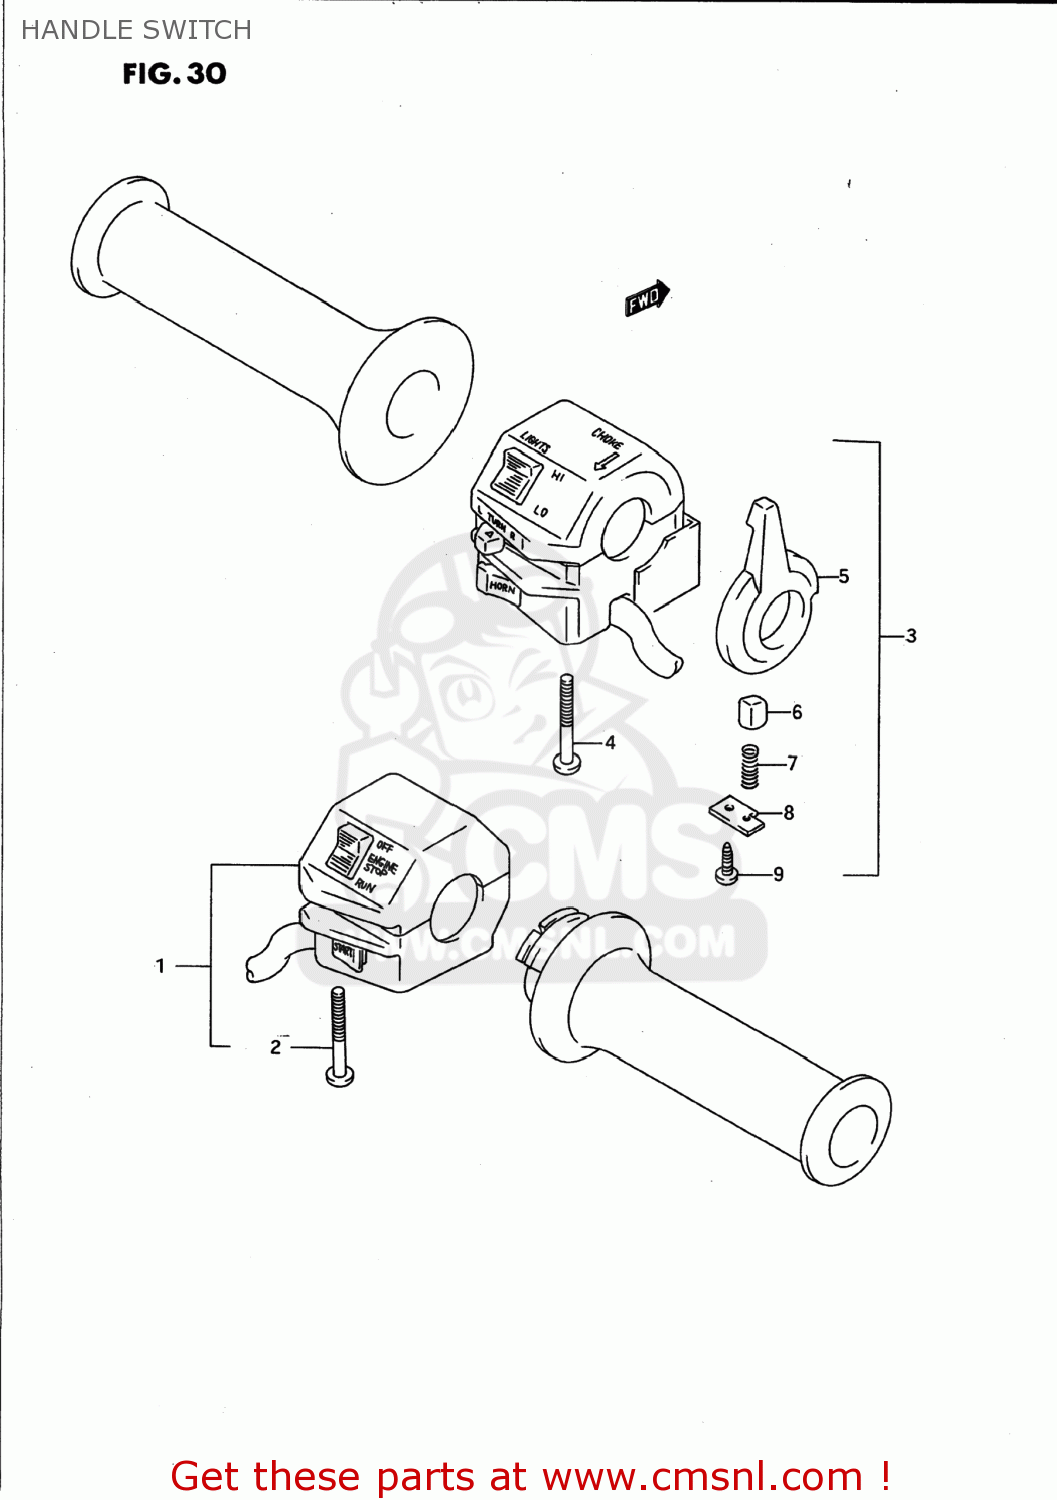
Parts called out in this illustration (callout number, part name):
1	SWITCH ASSEMBLY,HANDLE,RIGHT
2	SCREW, 5X45
3	SWITCH ASSY, HANDLE,LH
4	SCREW, 5X45
5	LEVER,CHOKE
6	PIECE,SLIDE
7	SPRING
8	PLATE
9	SCREW, TRUNK BOX
